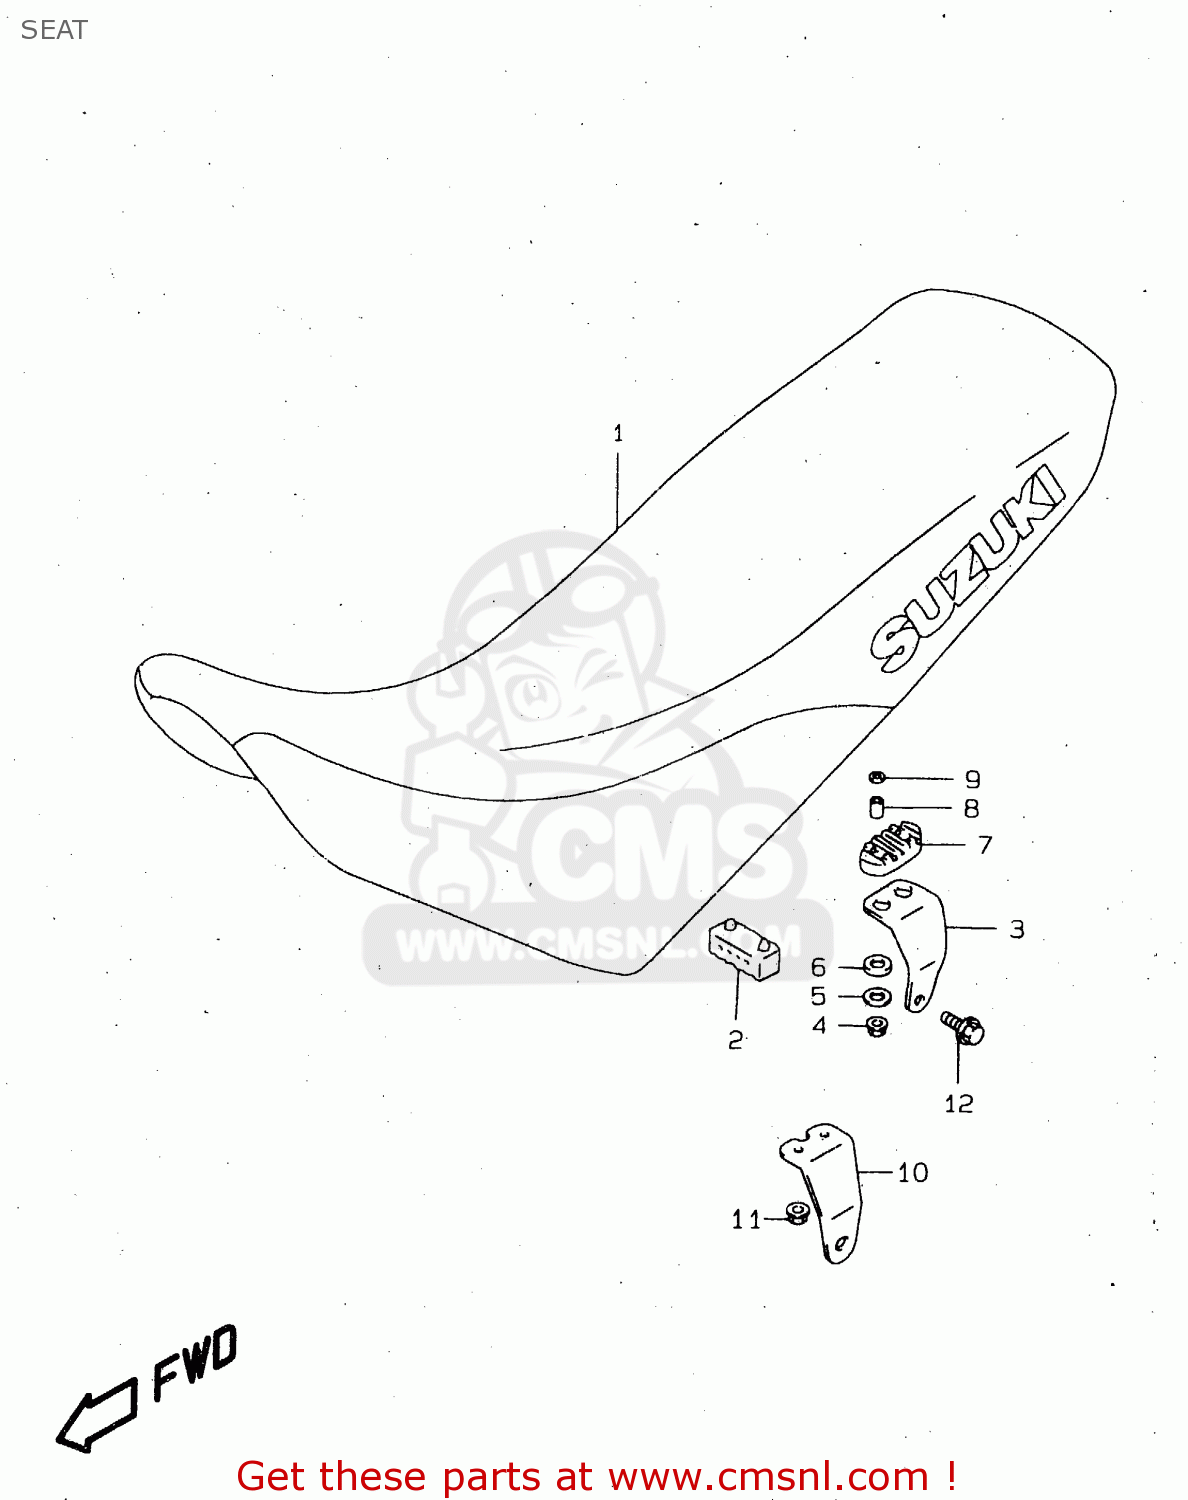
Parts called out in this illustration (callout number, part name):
1	SEAT SET
2	CUSHION,SEAT(40X20X15)
3	BRACKET,SEAT
4	NUT
5	WASHER(6.5X20X1.6)
6	CUSHION,SEAT
7	CUSHION,SEAT
8	SPACER,SEAT
9	WASHER
10	BRACKET
11	NUT
12	BOLT
